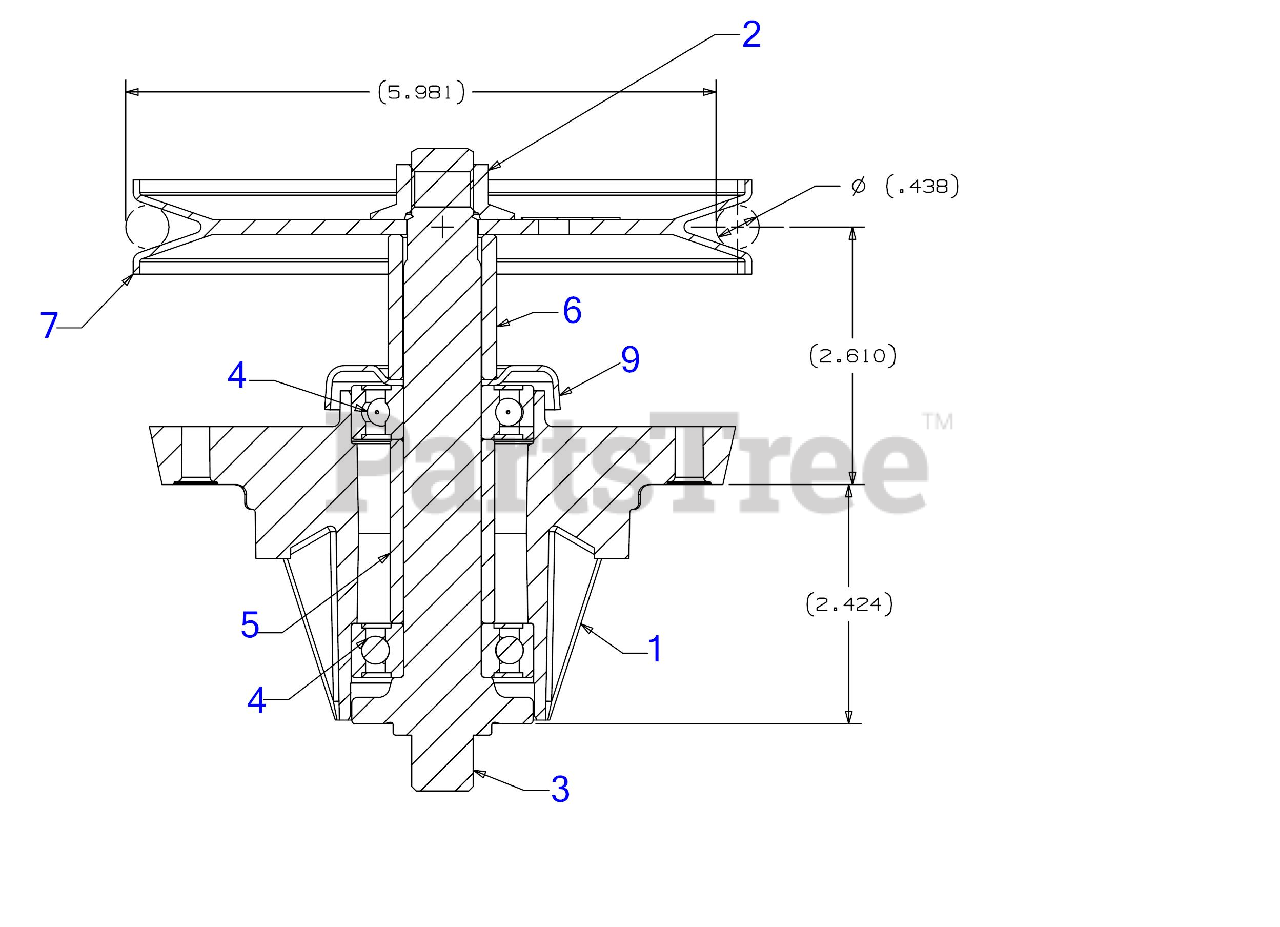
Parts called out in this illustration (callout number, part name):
1	DECK SPINDLE HOUSING
2	FLANGE NUT 5/8-18
3	SPINDLE SHAFT STAR 5.83 LG
4	BALL BEARING
5	SPACER- .792 x 1.060 x 1.860
6	SPACER .800 x 1.100 x 1.470 LG
7	DECK PULLEY 6.74" DIA
9	SHIELD-BRG DECK
